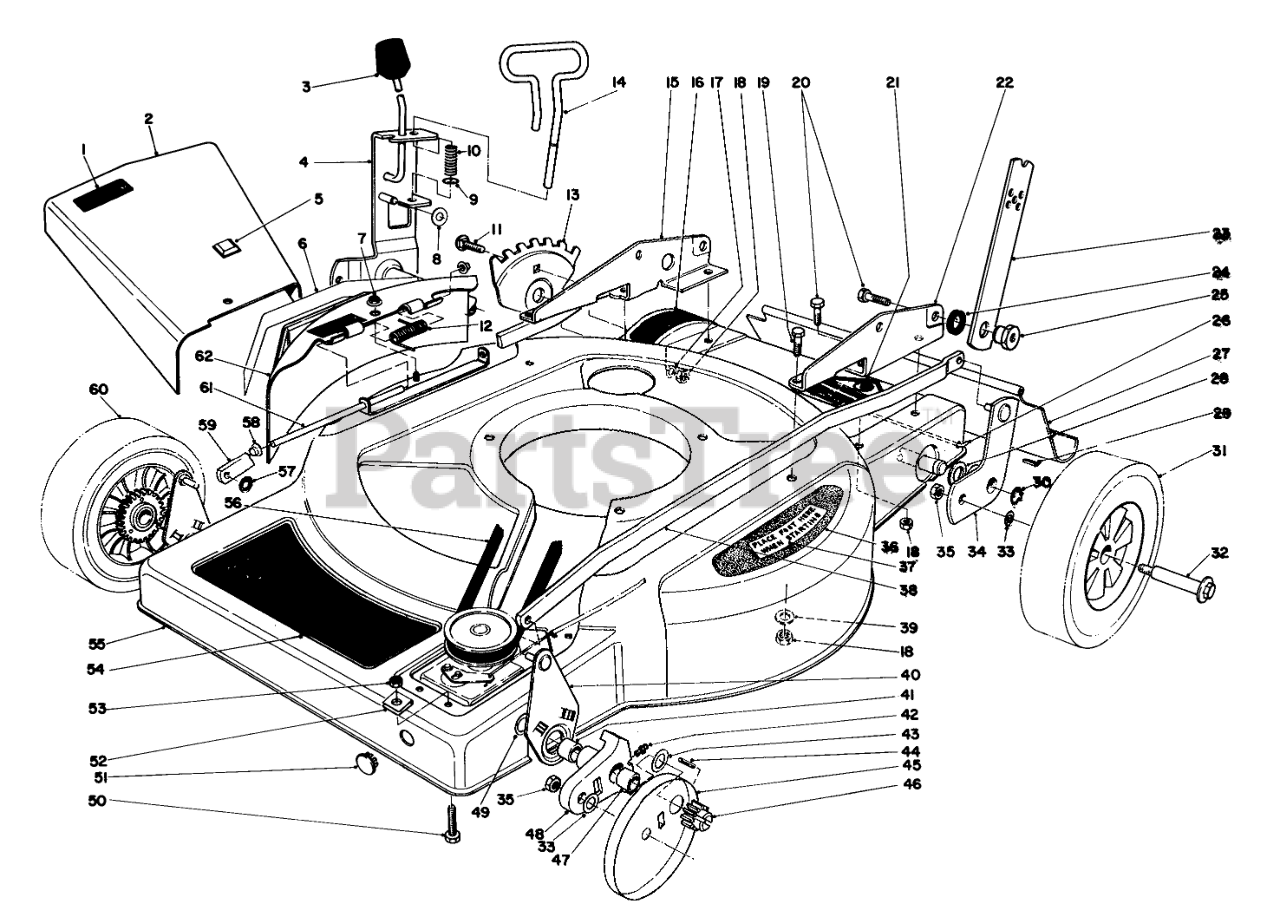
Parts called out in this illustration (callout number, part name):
1	Decal-Danger
2	Deflector-Grass (Incl. Ref. #1 & 5)
4	Pivot Arm
5	Bumper
6	Decal-Cover
8	WASHER-FLAT
9	E-RING
10	SPRING-COMPRESSION
11	Carriage Bolt
12	Spring
13	HOC ADJUSTMENT PLT
14	STOP ROD
15	Bracket Handle R.H.
16	Decal Height of Cut
17	WASHER-PLAIN
18	NUT-LOCK, CONE
19	SCREW-HH
20	SCREW-HH
21	DECAL-DANGER
22	Bracket-Handle R.H.
23	HANDLE LATCH
24	HANDLE LATCH SPACER
25	HANDLE PIVOT NUT
26	SHIELD ROD
27	SHIELD - TRAILING
28	WASHER-FLAT
29	KEY-SQUARE
30	RING-RETAINING
31	WHEEL TIRE ASM 8 IN
32	BOLT-WHEEL
33	WASHER
34	Pivot Arm
35	Nut
36	PAD STEP
37	Decal Step Pad
38	Spanner Link L.H.
39	WASHER-FLAT
40	PIVOT ARM LINK WA
41	BUSHING
42	FITTING-GREASE
43	WASHER-THRUST
44	Pin
45	WHEEL COVER
46	Pinion
47	BUSHING
48	Pivot Arm Assembly (Incl. Ref. #41, 42 & 47)
49	SHAFT RETAINER
50	SCREW
51	Hole Plug
52	SPEED NUT
53	NUT-JAM
54	DECK DECAL
55	Housing (Incl. Ref. #16, 21 & 36-37)
56	V BELT
57	NUT-PUSH
58	PUSHNUT-CAP, WASHER
59	Spanner Link R.H.
60	WHL/GEAR/TIRE PKG
61	DEFLECTOR PIVOT ROD
62	Mulcher Cover
